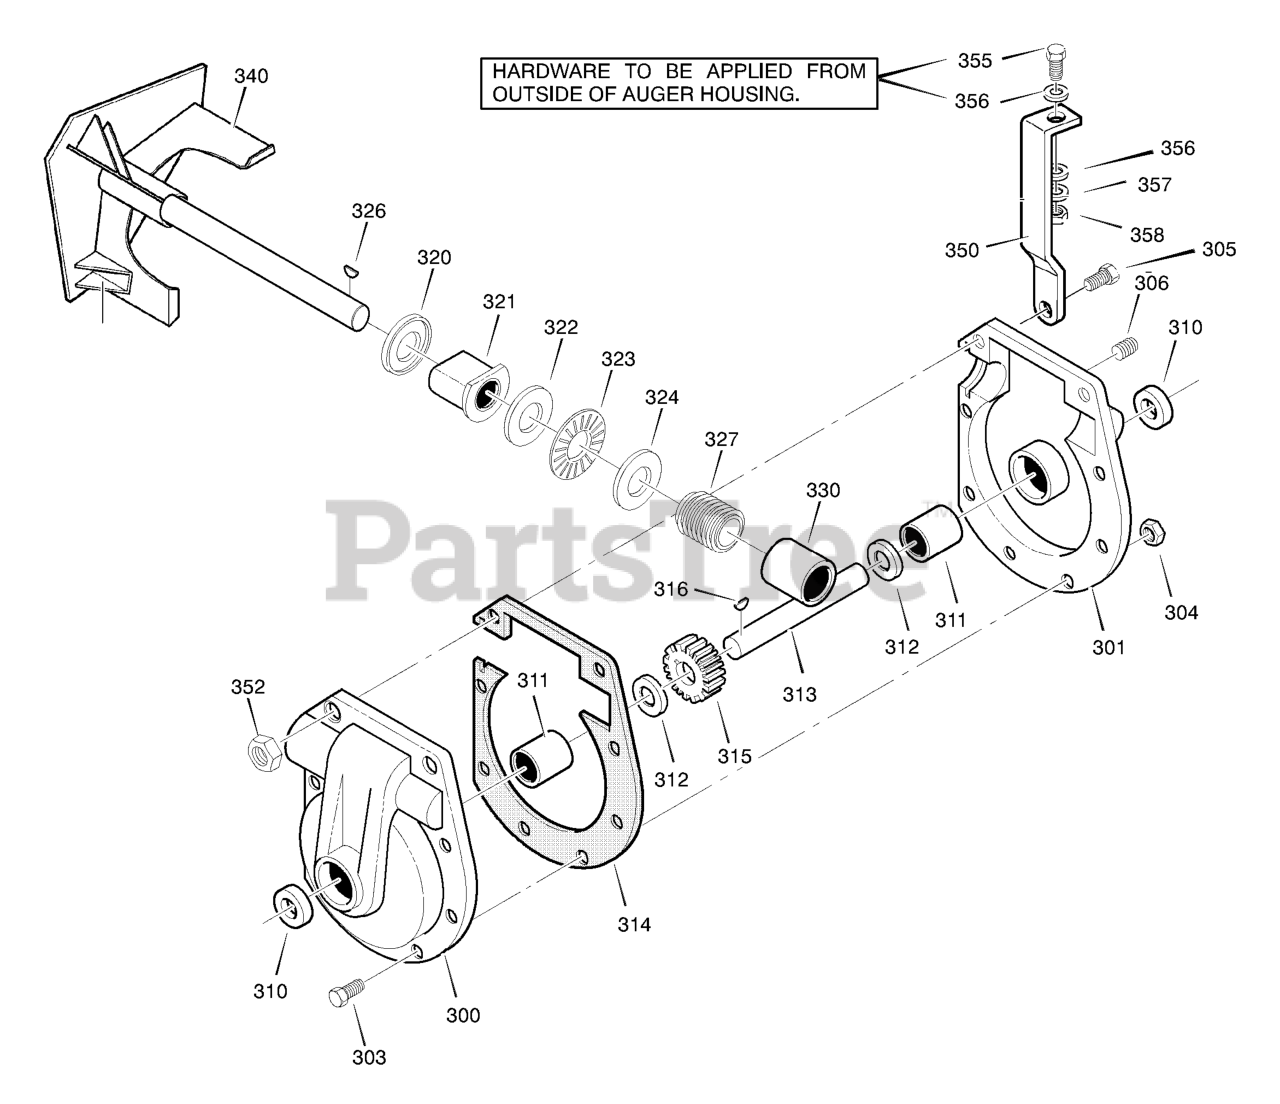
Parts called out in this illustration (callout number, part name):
300	CASE, GEAR, RH
301	CASE, GEAR, LH
303	SCREW,1/4-20X.75
304	NUT,1/4-20
305	SCREW, 5/16-24 x 1.75
306	SCREW, 3/8-16 x 0.50
310	SEAL, OIL
311	BEARING, FL
312	WASHER, FLAT
313	SHAFT, AUGER OUTPUT
314	GASKET, GEAR BOX
315	WORM GEAR
316	KEY, WOODRUFF #61
320	BRNG, FL
321	SHAFT, AUGER INPUT
322	COLLAR, THRUST
323	PIN, SPRING
324	WASHER, FLAT
326	BRNG, FL
327	SEAL, OIL
330	BEARING
350	LF BRACE, GEAR BOX
352	NUT, 5/16-24
355	SCREW 5/16-18X1.25
356	WASHER
357	WASHER
358	NUT 5/16-18
